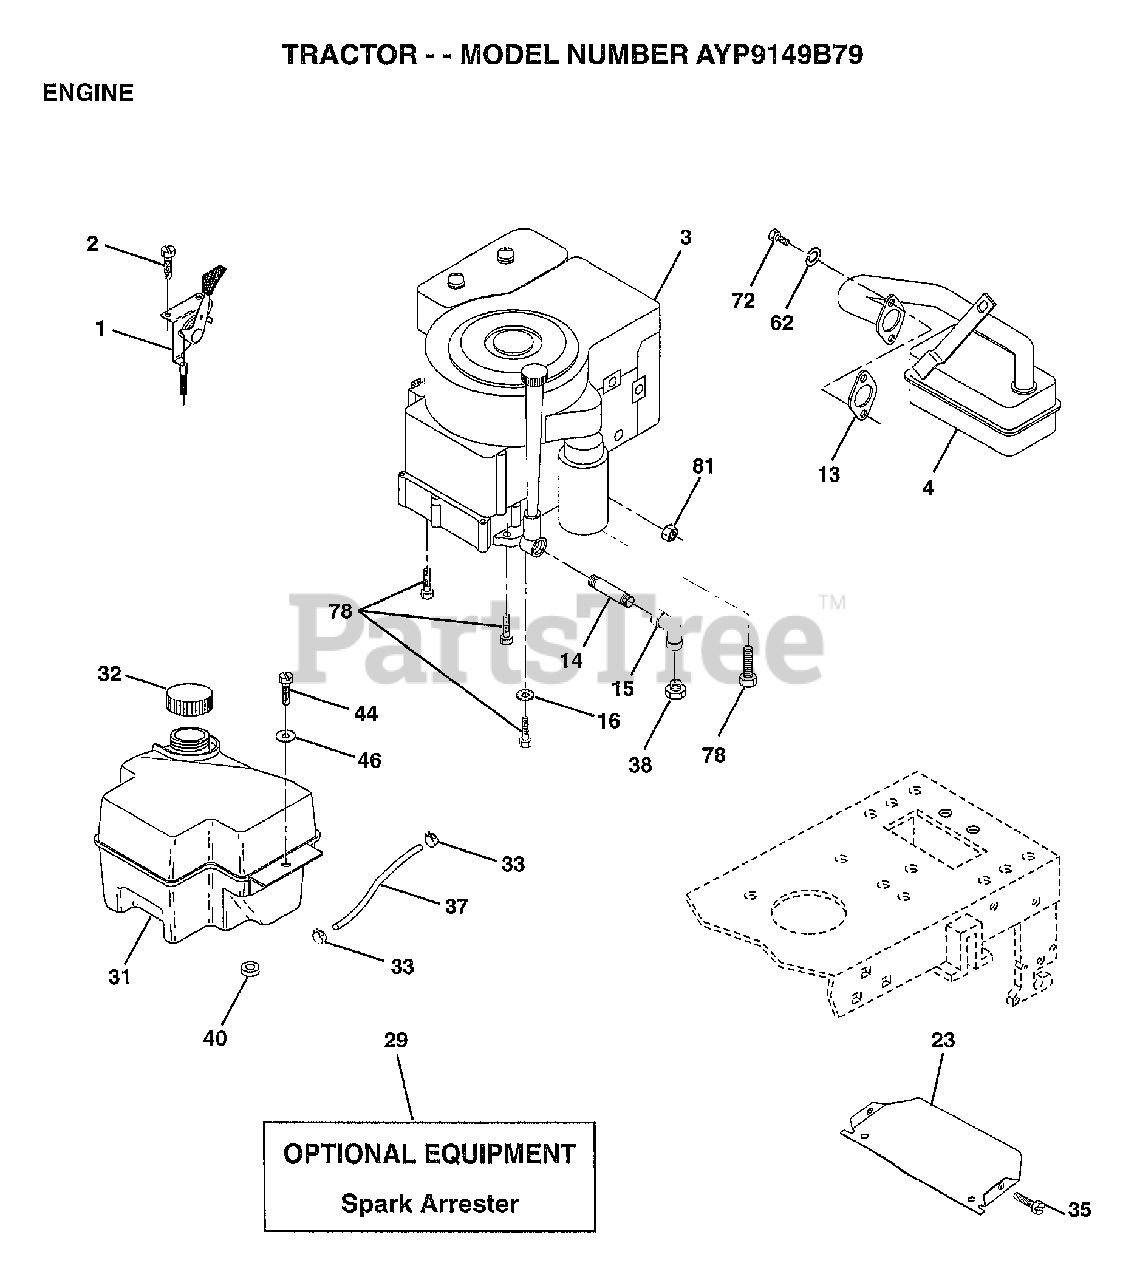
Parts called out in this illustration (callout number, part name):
1	CONTROL THROTTLE
2	SCREW LT
4	MUFFLER
13	GASKET ENG 1 313 LD TIN PLATED
14	PIPE NIPPLE
15	ELBOW
16	LOCKWASHER
23	SHIELD-HEAT
32	CAP ASM FUEL
33	HOSE CLAMP
35	SCREW
37	LINE FUEL
44	SCREW HEX CRT
46	WASHER
62	LOCKWASHER
72	SCREW
78	SCREW
81	NUT
